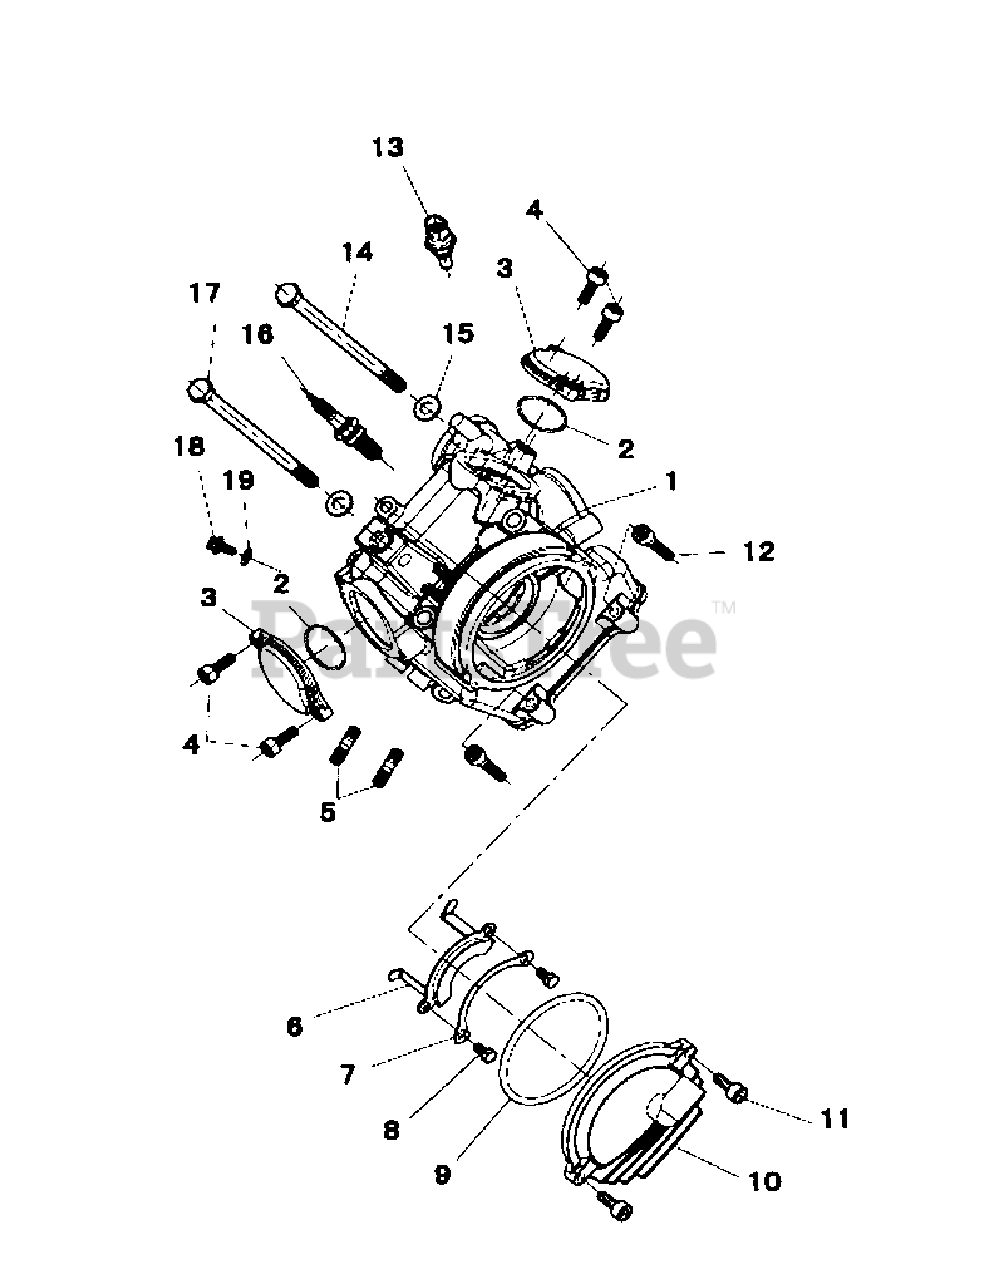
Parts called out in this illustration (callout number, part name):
1	Cylinder Head-Comp (EFI Engine)
2	O-Ring 58X2.4
3	Cover-Inlet Valve
4	Screw-Cylinder M6 X 20 Inner
5	Studbolt M8X45
6	Pressure Plate-Camshaft
7	Bolt Limit Board
8	Hexagon Head Bolt M6X16
9	O-Ring 107X2.4
10	Cover-Cylinder Head Lh
11	Screw-Cylinder M6 X 25 Inner
12	Screw-Cylinder M8 X 40 Inner
13	Sensor-Water Temperature
14	Bolt M10X1.25X250
16	Sparkplug(Ngk dr8Ea)
17	Bolt M10X1.25X223
18	Flangebolt M6X12
19	Aluminum Washer
